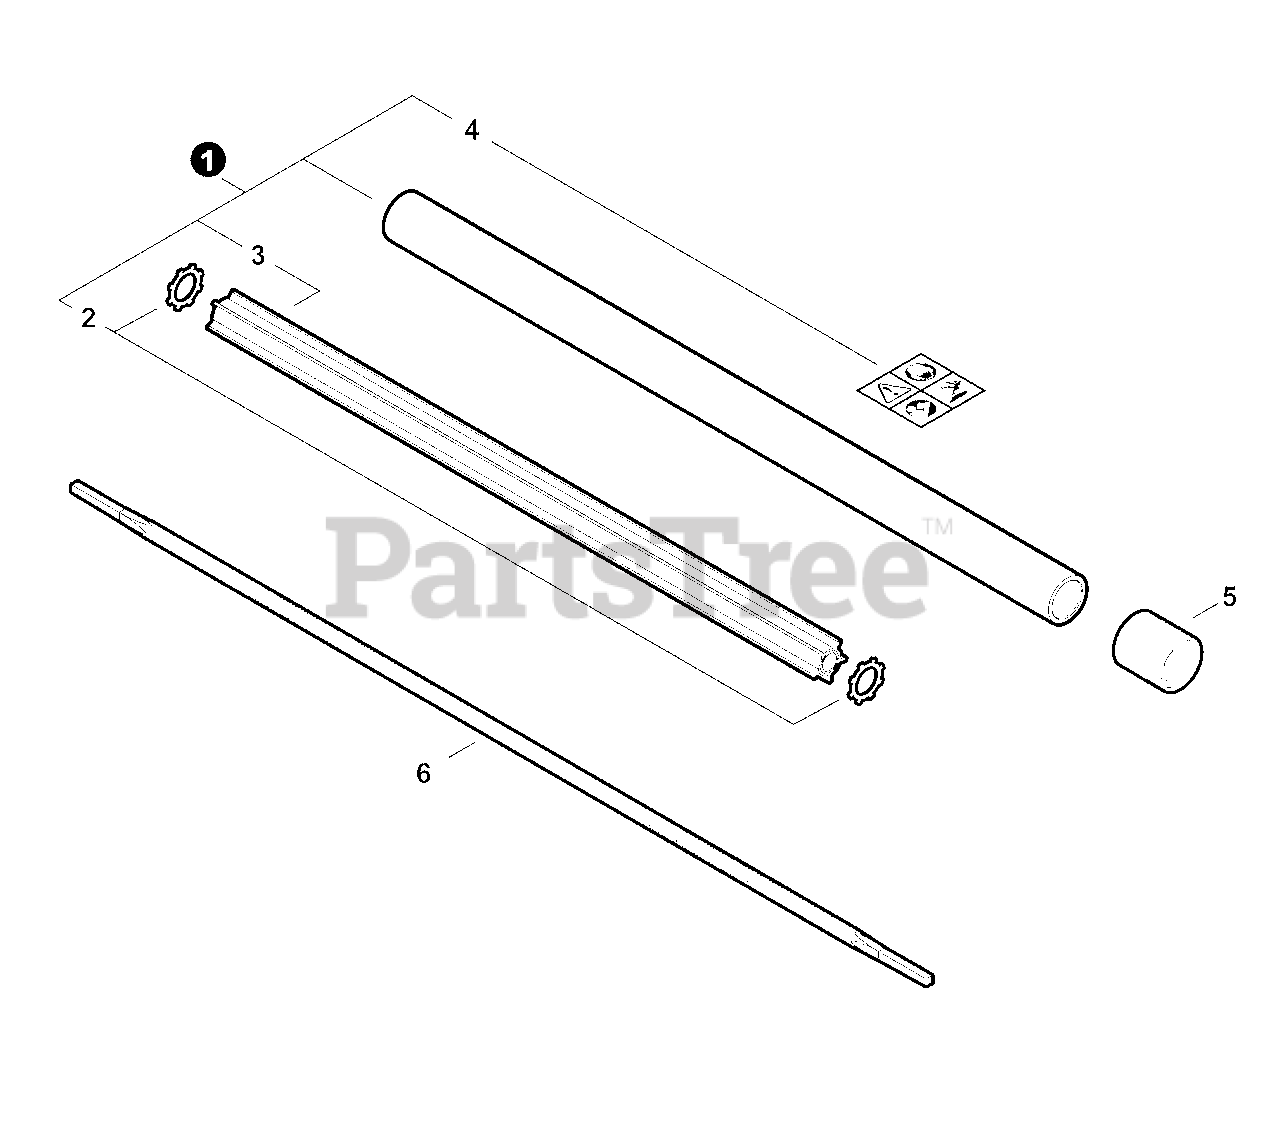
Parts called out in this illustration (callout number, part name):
1	MAIN PIPE ASSY
4	LABEL, CAUTION
5	TUBE, FLEXIBLE
6	DRIVESHAFT - FLEXIBLE
